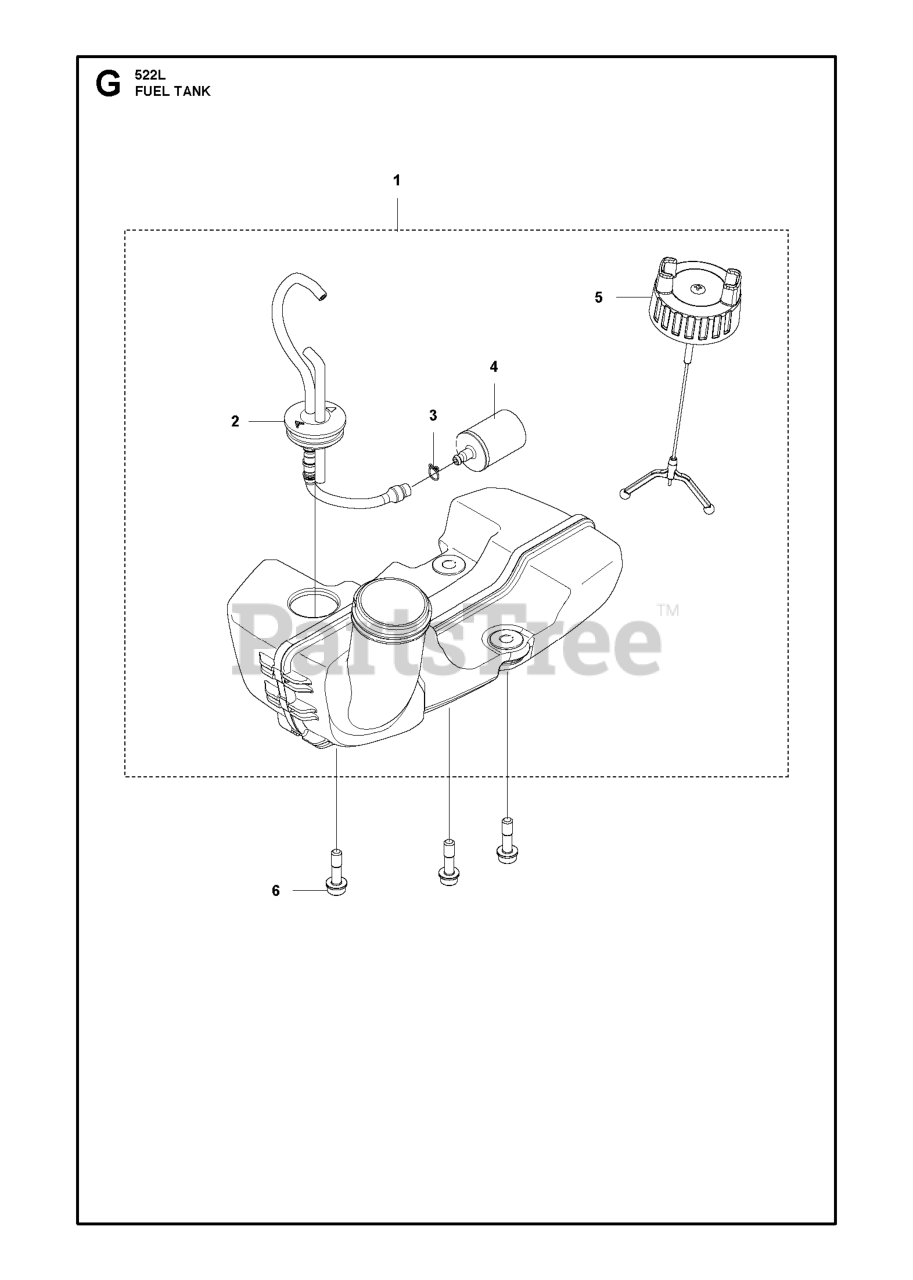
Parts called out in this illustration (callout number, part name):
2	PIPE COMP
4	RP FUEL FILTER
6	BOLT
